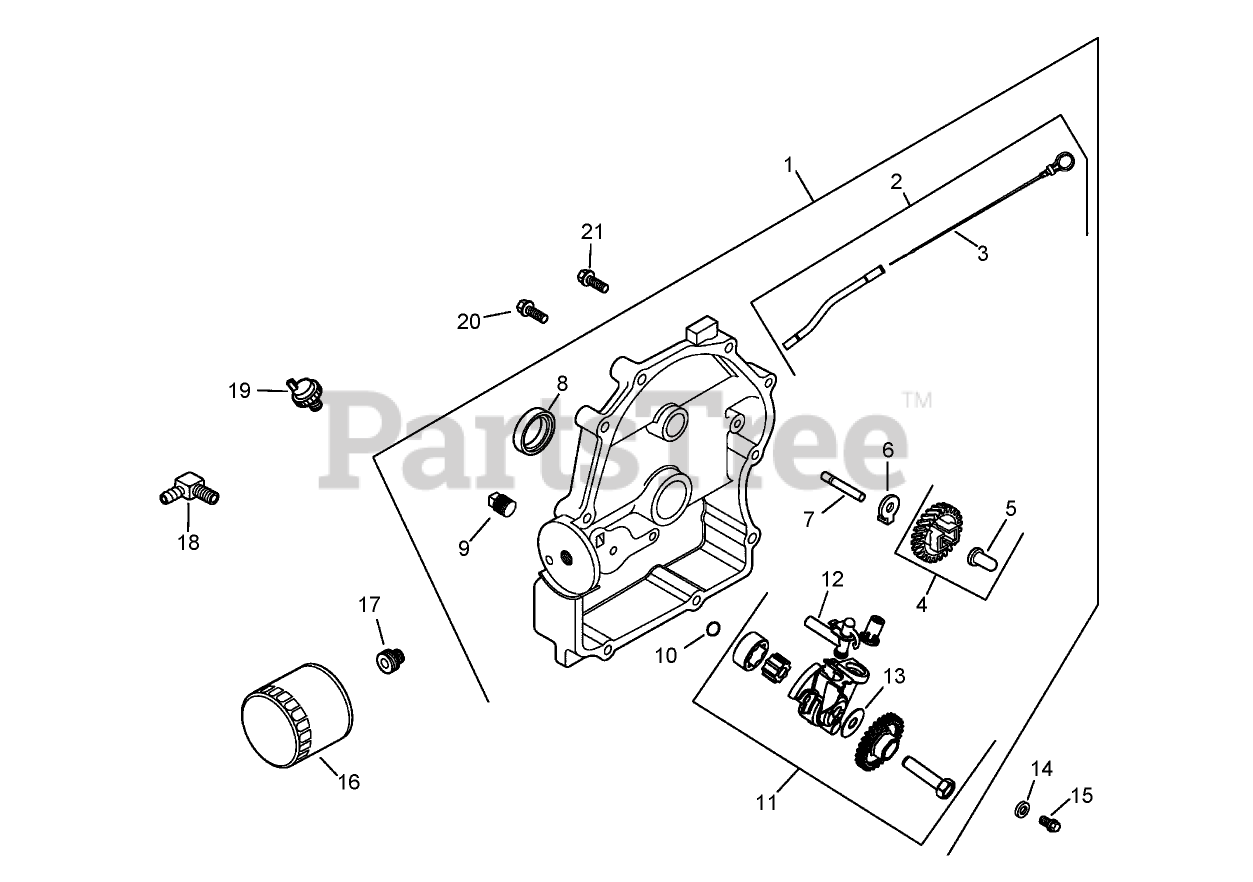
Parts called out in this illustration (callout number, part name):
1	Closure Plate Kit (Includes 2-13)
2	Dipstick Tube ASM (Includes 3)
3	Dipstick
4	Governor Gear Kit (Includes 5)
5	PIN-REGULATING, GOVERNOR
6	TAB-LOCKING
7	SHAFT-GEAR, GOVERNOR
8	SEAL-OIL (P-T-O END)
9	PLUG-PIPE, COUNTERSUNK (1/8)
10	O-Ring
11	Oil Pump ASM (Includes 12, 13)
12	TUBE-PICK UP, OIL
13	O-RING
14	WASHER-FLAT (6 MM)
15	SCREW-FLANGE, THREAD FORMING (M6X1.0X25)
16	Filter-Oil
17	Nipple-Filter, Oil
18	Connector-Hose, 90 Deg
19	SWITCH-PRESSURE, OIL
20	Screw-HF (M8x1.25x45)
21	SCREW-FLANGE (M8X1.25X45)
